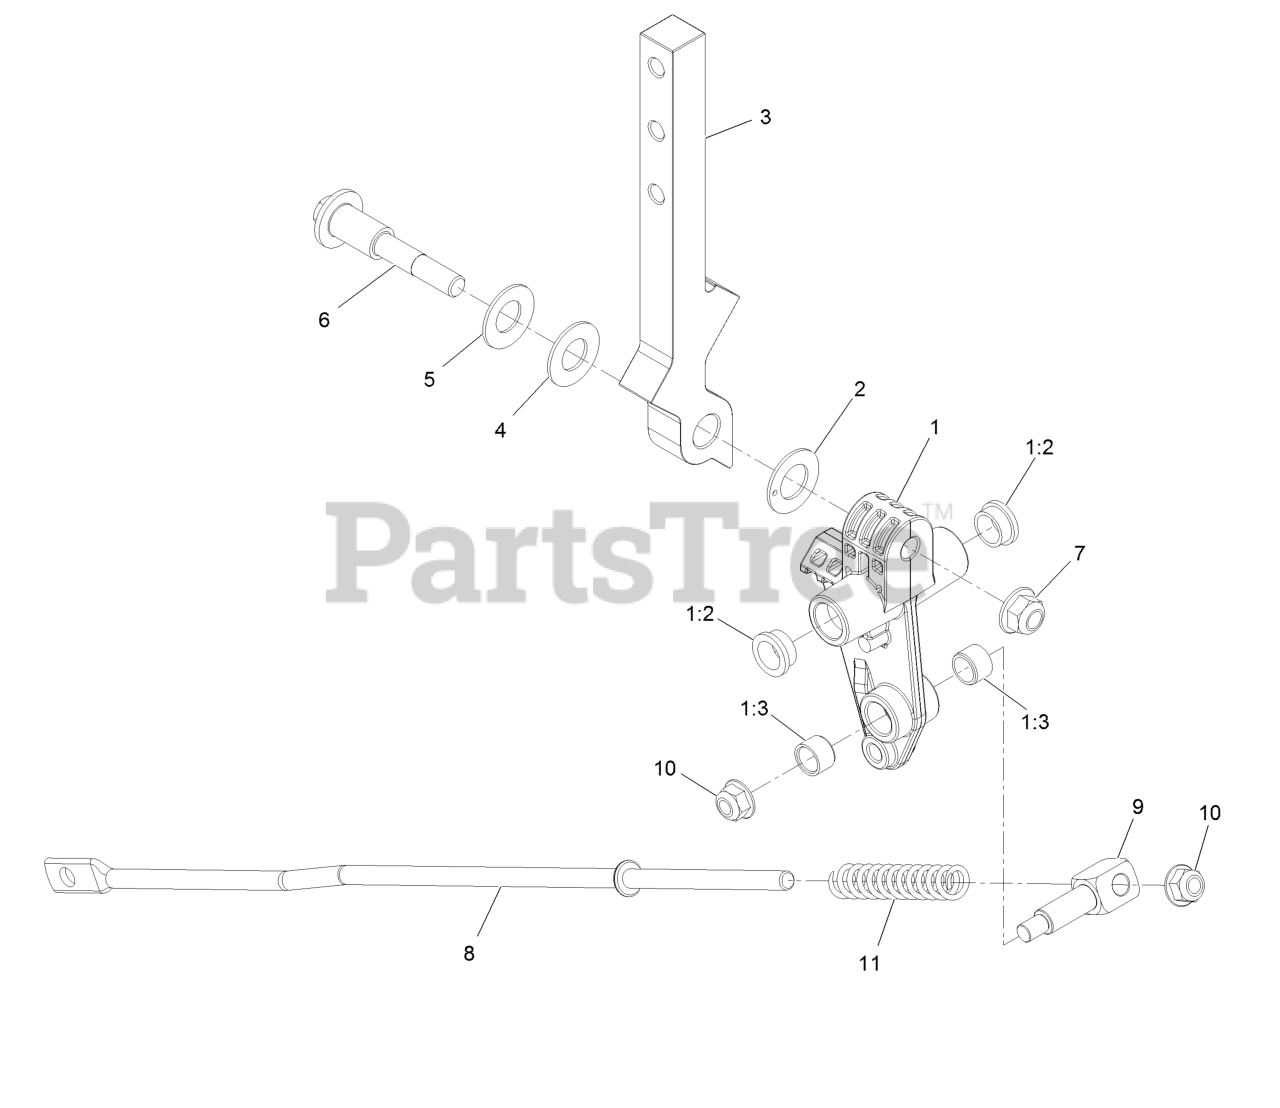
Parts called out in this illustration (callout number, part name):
1	Control Arm ASM
1:2	Bushing
1:3	Bushing-Sleeve
2	Washer-Friction
3	Arm-Control
5	Washer-Belleville
6	Bolt-Pivot
7	Nut-Nyloc 3/8-16 Flg
8	Link-Control
10	Nut-Nyloc 5/16-18 Flg
11	Spring-Return, Neutral
